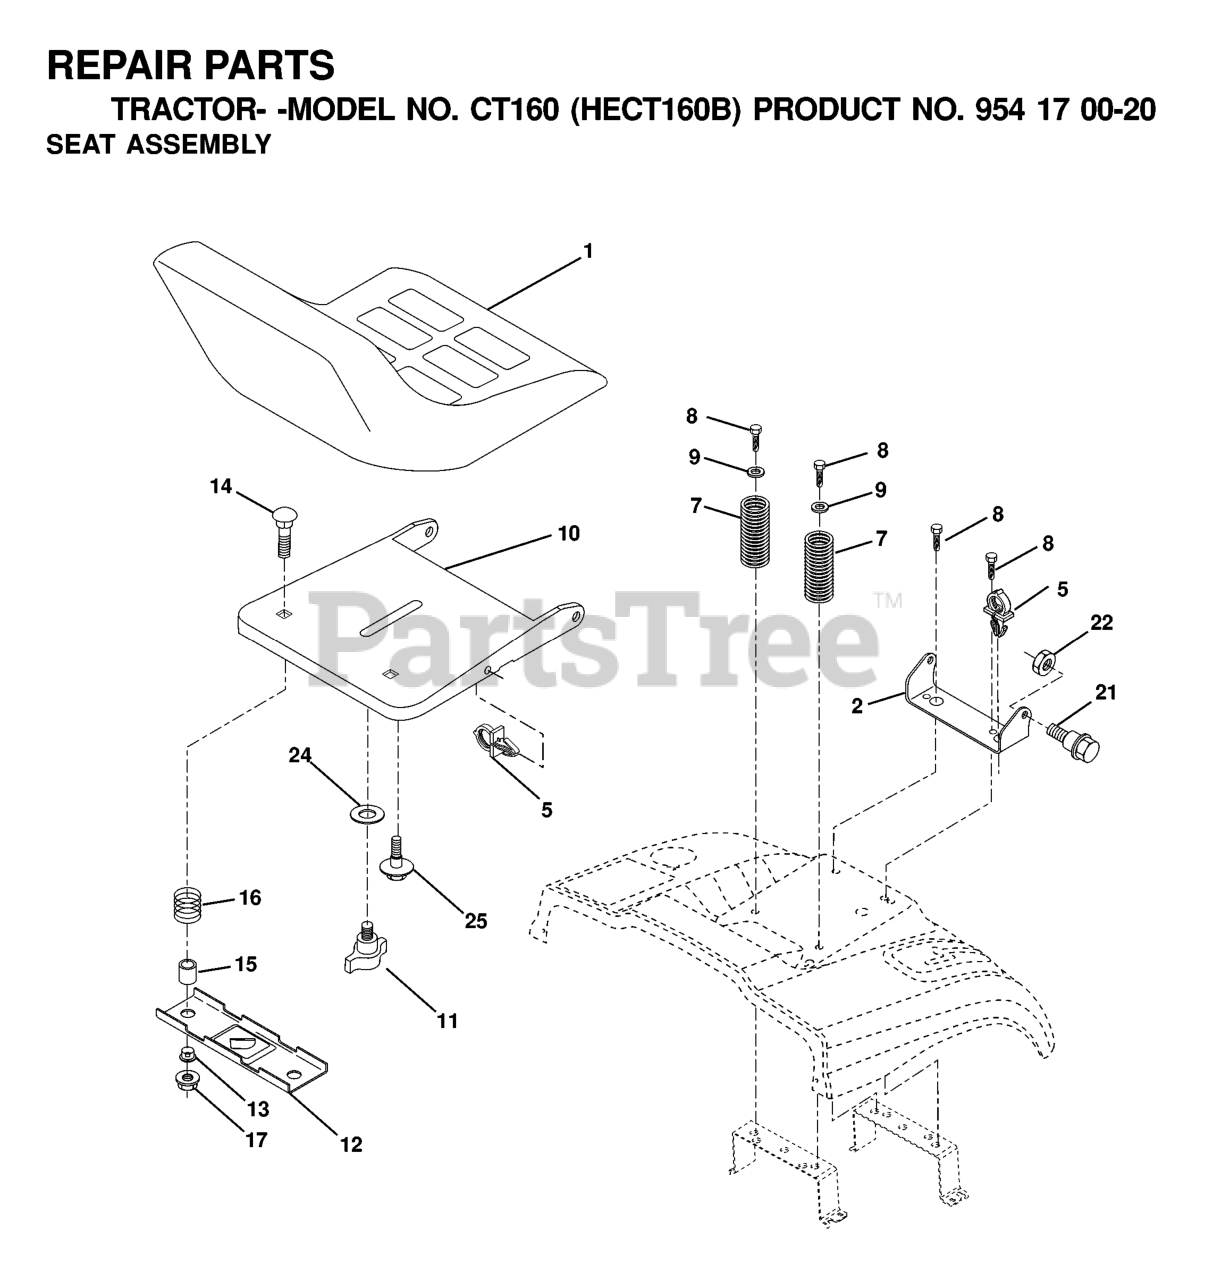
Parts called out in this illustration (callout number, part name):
1	SEAT, GRAY
2	SEAT PIVOT BRKT
7	SPRING COMPRESSION
8	SCREW 3/8-16X1
9	WASHER
10	PAN, SEAT
11	KNOB.SEAT.ADJ.WINGNUT
12	BRKT SWITCH
14	BOLT.ROUND.HEAD.SQUARE.NECK
15	SPACER SPLIT
16	SPRING COMPRESSED
17	NUT T
21	BOLT.SHOULDER.5/16-18
22	NUT.71038.31-18.HEX.NYLOCK
24	WASHER GT
25	BOLT,SHOULD
